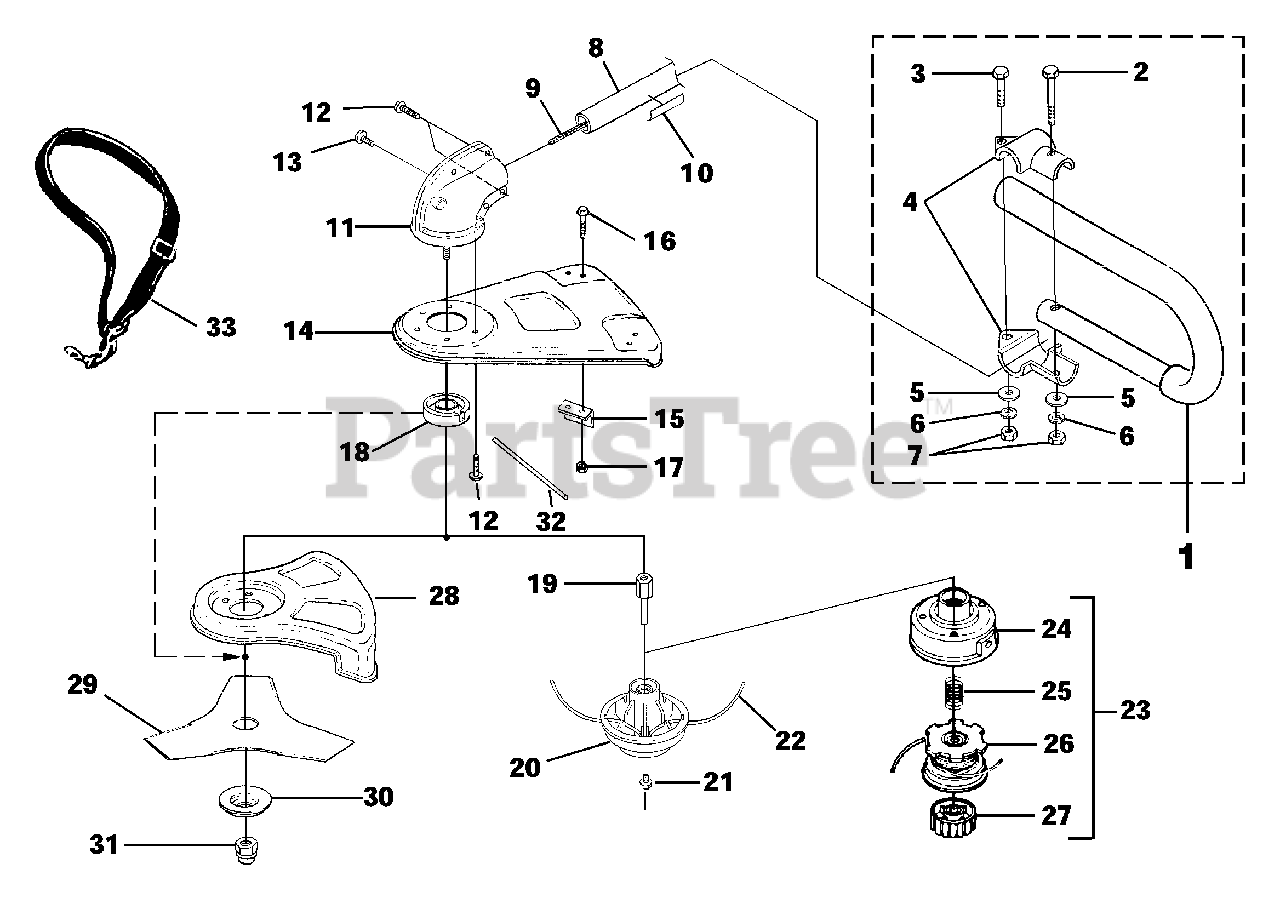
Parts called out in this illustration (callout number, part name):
1	HANDLE ("J")
2	SCREW-Hex Hd. (1/4-20 X 1 1/2")
3	SCREW-Hex Hd. (1/4-20 X 1")
4	CLAMP-Handle Bar
5	WASHER-Flat (1/4")
6	WASHER-Lock (1/4")
7	NUT-Hex (1/4-20)
8	DRIVESHAFT HOUSING
9	DRIVESHAFT-Flexible
10	DECAL-Warning
11	GEAR HEAD
12	Screw, Taptite Hex Hd. (10-24 x 1/2")
13	Screw-Hex Hd. (10-24 x 5/8")
14	GRASS DEFLECTOR KIT
15	BLADE-Cut-Off
16	SCREW-Mach. Hex Hd. (10-24 X 3/8")
17	NUT-Hex (10-24)
18	WASHER-Flanged
19	ADAPTER-Shaft
20	STRINGHEAD-Pro-Cut w/line (UT15151, UT15154, UT20722, UT20723, UT15157)
21	SCREW-(5/16-18 x 5/8")
22	LINE-Replacement
23	STRINGHEAD-Complete (.095") (UT15152, UT15160, UT15159R, UT15204)
24	HOUSING & EYELET (Dual Line)
25	SPRING-Compression
26	SPOOL & STRING (.095")
27	RETAINER-Spool (R.H. Thread, Black)
28	BLADE GUARD
29	BLADE-Tri-Arc(TM)
30	WASHER-Cupped (Lower)
31	NUT-Hex (5/16-18) (R.H.)
32	TOOL-Holding Pin
33	HARNESS
